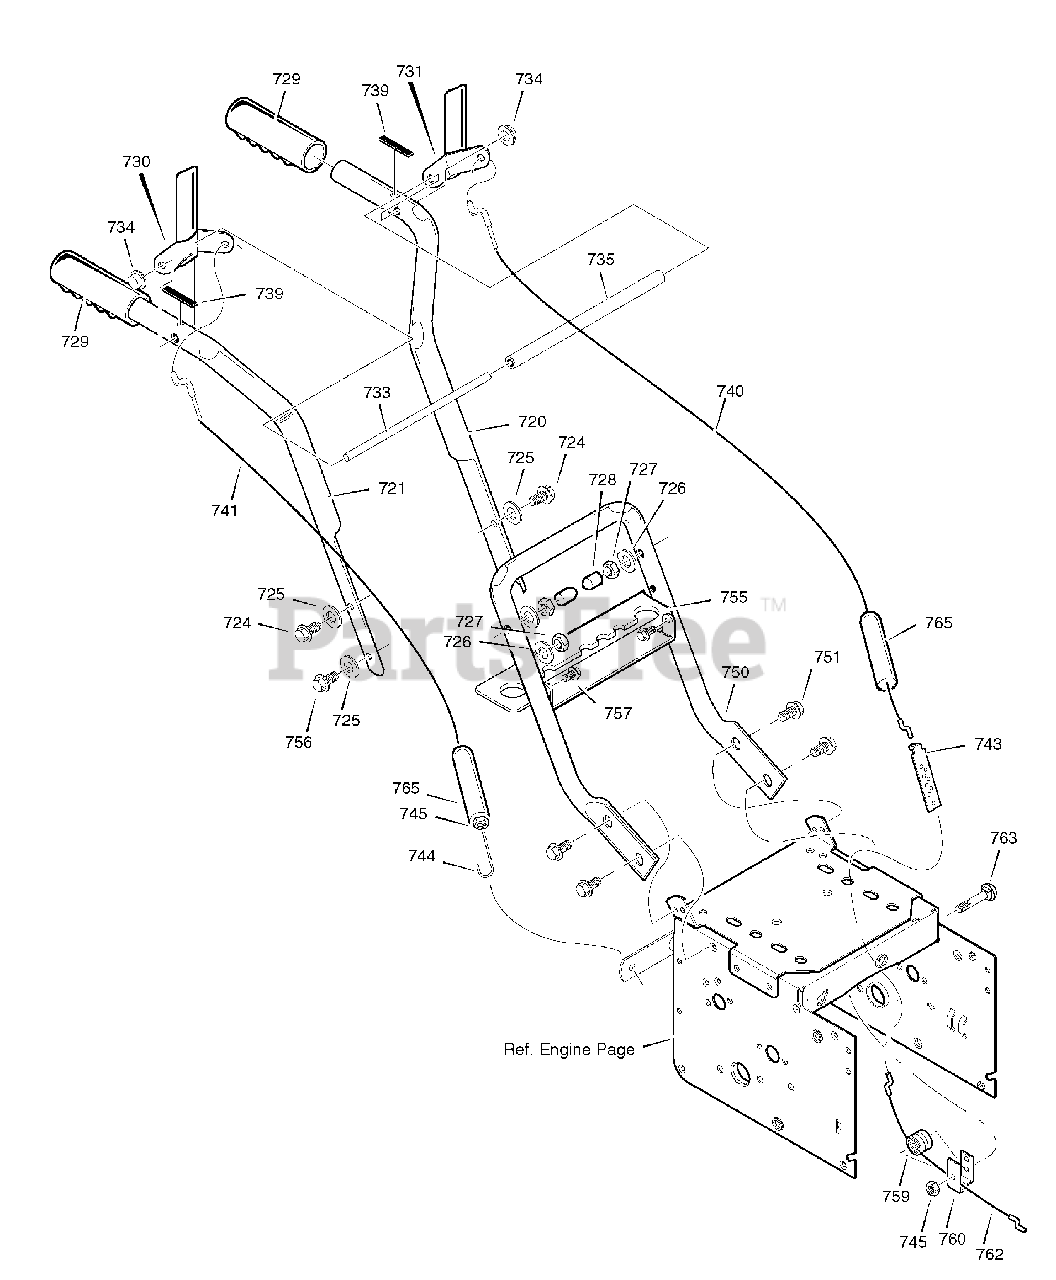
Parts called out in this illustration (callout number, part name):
720	HANDLE, UPPER LH
721	HANDLE, UPPER RH
724	SCREW, 5/16-18 x 2.75
725	WASHER, FLAT
726	WASHER, SPTLK .31X.58X.08
727	NUT, 5/16-18 REGHEX
728	STOP, RED PLASTIC
729	GRIP, HANDLE FINGER
730	LEVER, ASSY CLUTCH DRIVE RH
731	LEVER, ASSY CLUTCH DRIVE LH
733	ROD, PIVOT CLUTCH
734	NUT, PUSH ON CAP
735	SPACER, HANDLE
739	BUMPER, RECTANGLE
740	CABLE, CLUTCH 28.44L
741	CABLE, AUGER CLUTCH
743	BRACKET, CABLE ADJUSTER
744	SPRING, AUGER CLUTCH
745	NUT, 1/4-20
750	HANDLE, LOWER
751	SCREW
755	BRKT, GEAR SELECTOR
756	SCREW, 5/16-18 x 2.00
757	SCREW, 1/4-20 X 0.63
759	SPOOL-CABLE, AUGER CLUTCH
760	BRACKET, CABLE SPOOL YZ
762	CABLE, LOWER DRIVE 12"
763	BOLT, HEX 1/4-20 X 1.50 YZ
765	BOOT, CLUTCH SPRING
